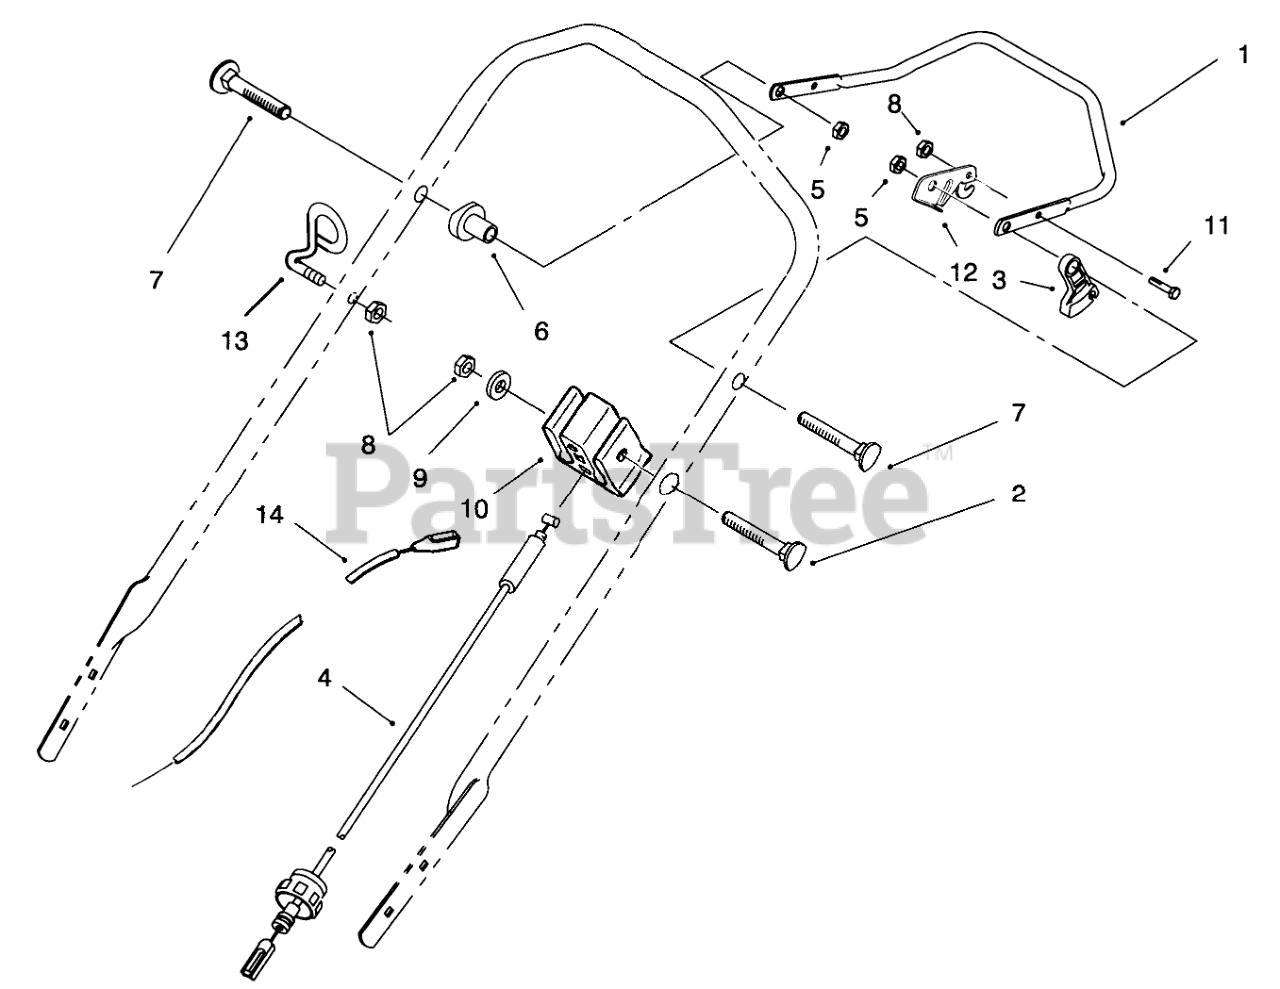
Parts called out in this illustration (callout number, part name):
1	Bar-Control
2	HANDLE SCREW
3	LEVER-TRACTION
4	CABLE-TRACTION
5	NUT-LOCK, NI
6	SPACER-SUPPORT
7	5/16-18 X 2 HNDLE SCREW
8	NUT-LOCK, NI
9	WASHER-FLAT
10	SUPPORT-CABLE
11	SCREW-HH
12	LEVER-CONTROL
13	ROPE GUIDE
14	BRAKE CONTROL
